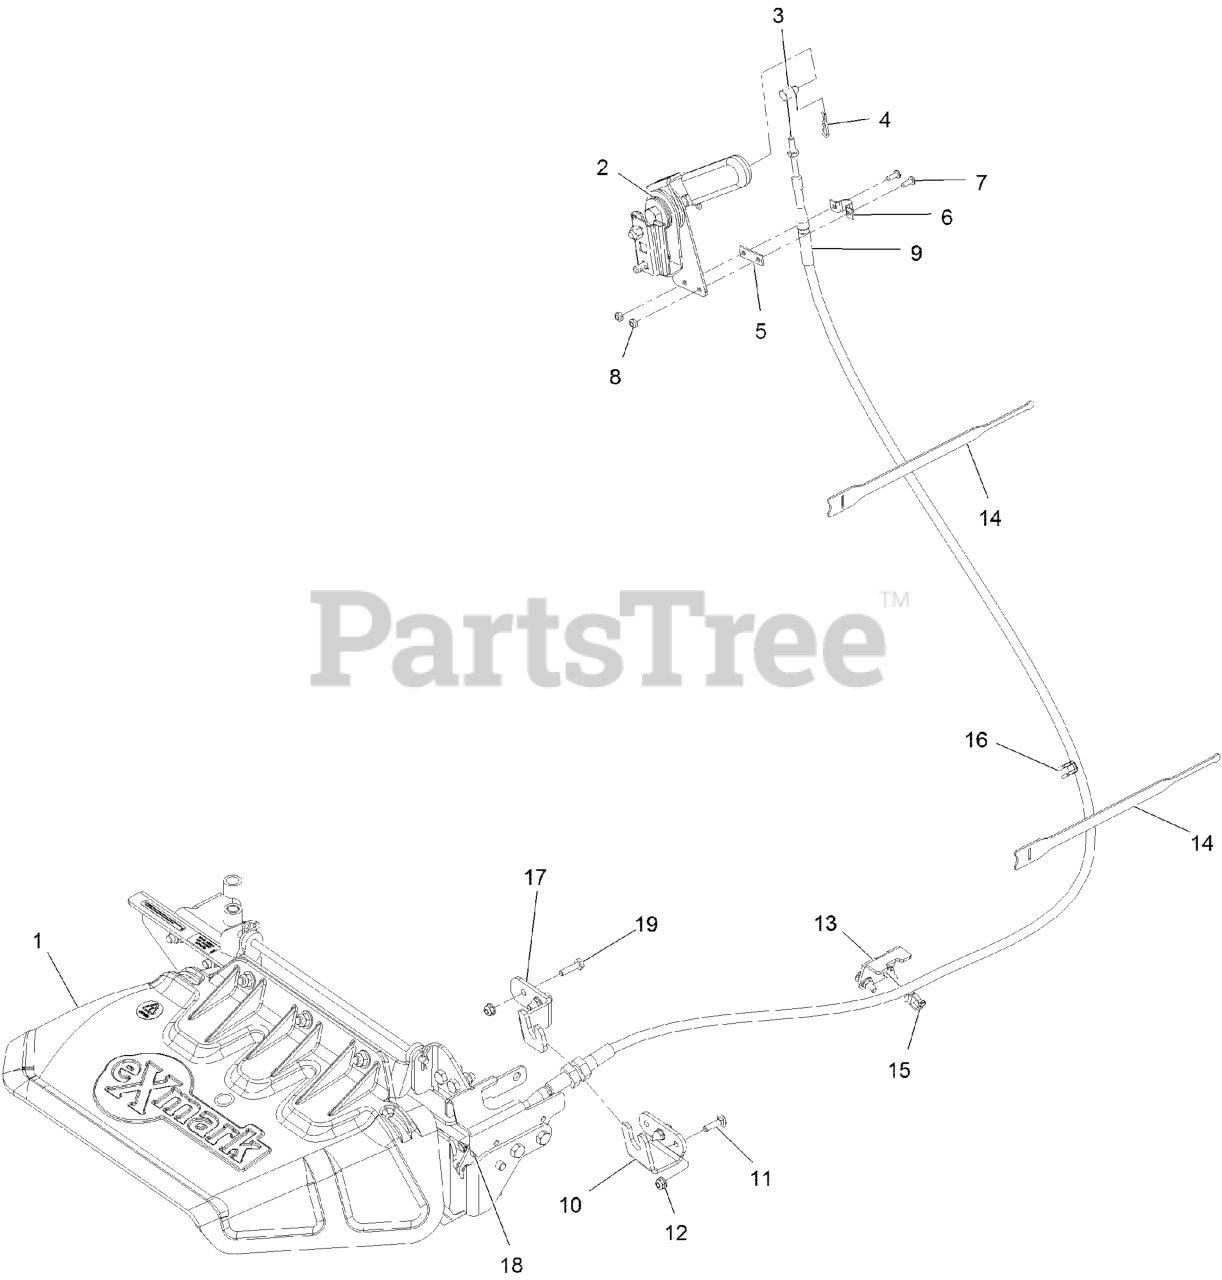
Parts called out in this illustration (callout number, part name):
1	ASM, OCD
2	ASM, HAND LEVER
3	PIVOT, CONTROL CABLE
4	PIN-COTTER
5	SHIM,CONTROL CABLE
7	SCREW-PPH
8	NUT-LOCK, NI
9	CABLE,DISCHARGE GATE
10	BRKT-OCD CABLE
11	SCREW-CARR
13	BRKT-CABLE
14	STRAP-VELCRO, CABLE TIE
15	CLIP-TIE
16	Clip-Edge
17	BRKT-OCD CABLE
18	NUT-LOCK
19	SCREW-HH
